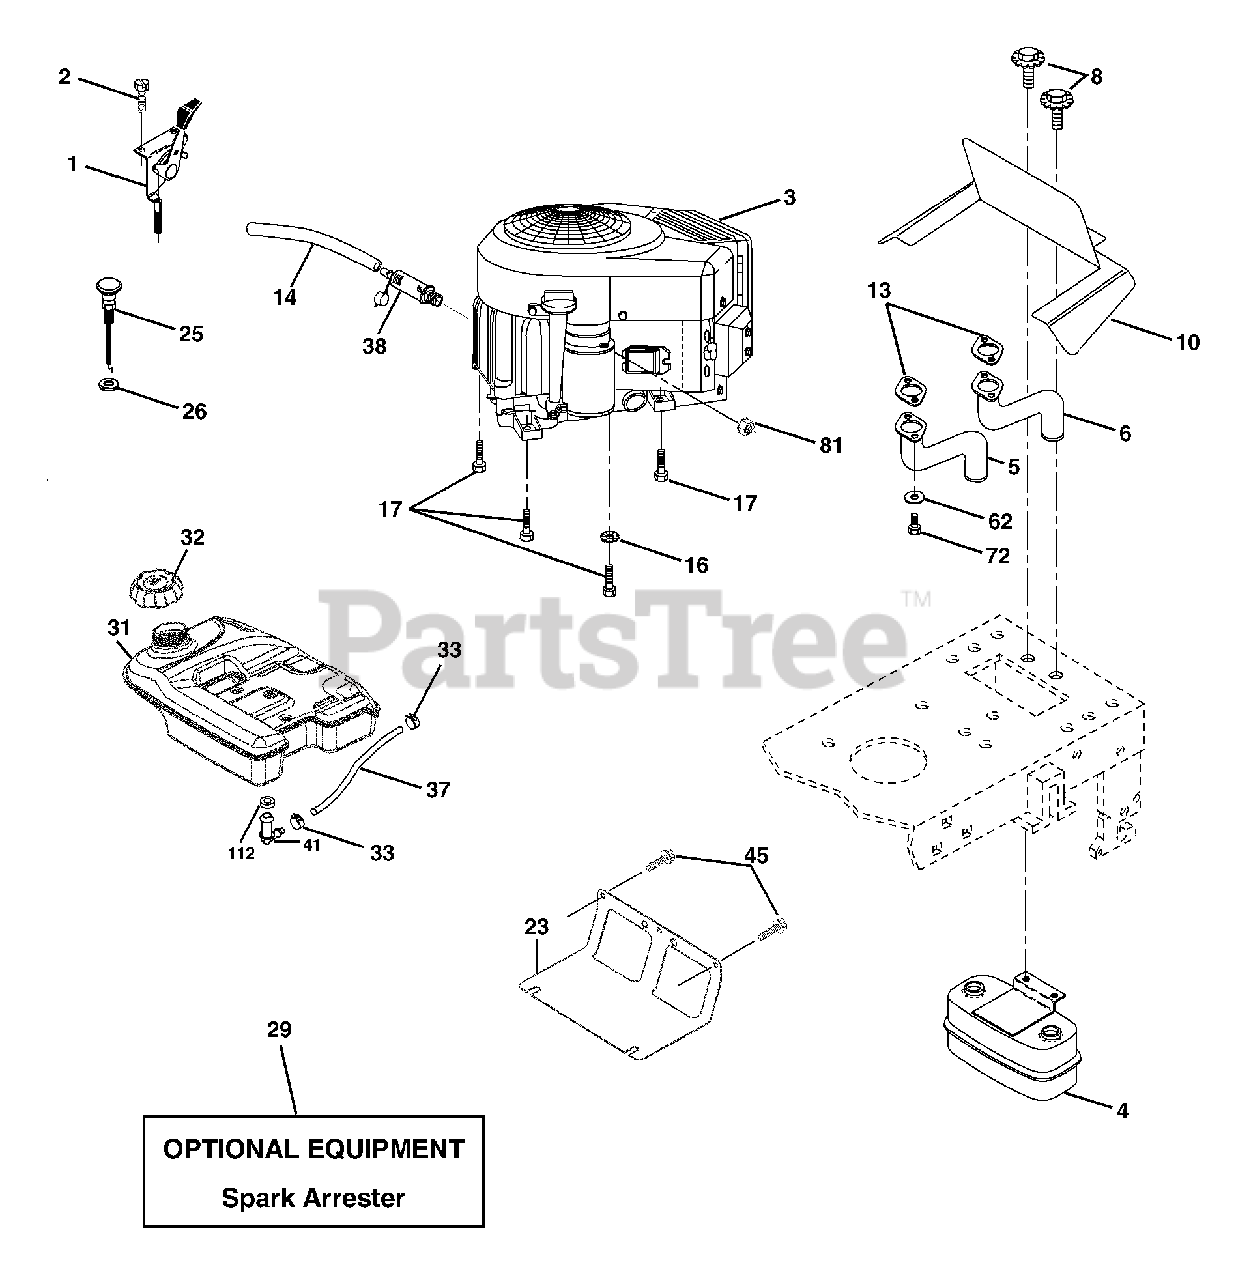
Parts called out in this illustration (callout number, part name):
1	Control Throttle
2	Screw Hwhd Hi-Lo #13-16 x 3/4
4	Muffl er Asm Twin Lo-Tone
5	Pipe Exhaust LH Intek
6	Pipe Exhaust RH Intek
8	Bolt 5/16-18 UNC x 3/4 w/Sems
10	Shield Browning Intek II
13	Muffl er Gasket
16	Washer Lock Ext Tooth 3/8
17	Screw Thdrol 3/8-16 x 1-1/2
23	Shield Heat
25	Choke Control
26	Nut, Keps 3/8-24 UNF
29	Kit Spark Arrestor (Flat Scrn)
31	Tank Fuel 5.0 Rear
32	Cap Asm Fuel
33	Clamp Hose Black
37	Line Fuel
38	Plug Drain Oil Easy
41	Stem Tank Fuel
45	Screw Hexwsh Thdr 3/8-16 x 3/4
62	Washer Lock 5/16
72	Screw Hex Hd Cap 5/16-18 x 3/4
81	Nut Keps Hex 1/4-20 UNC
112	Bushing
